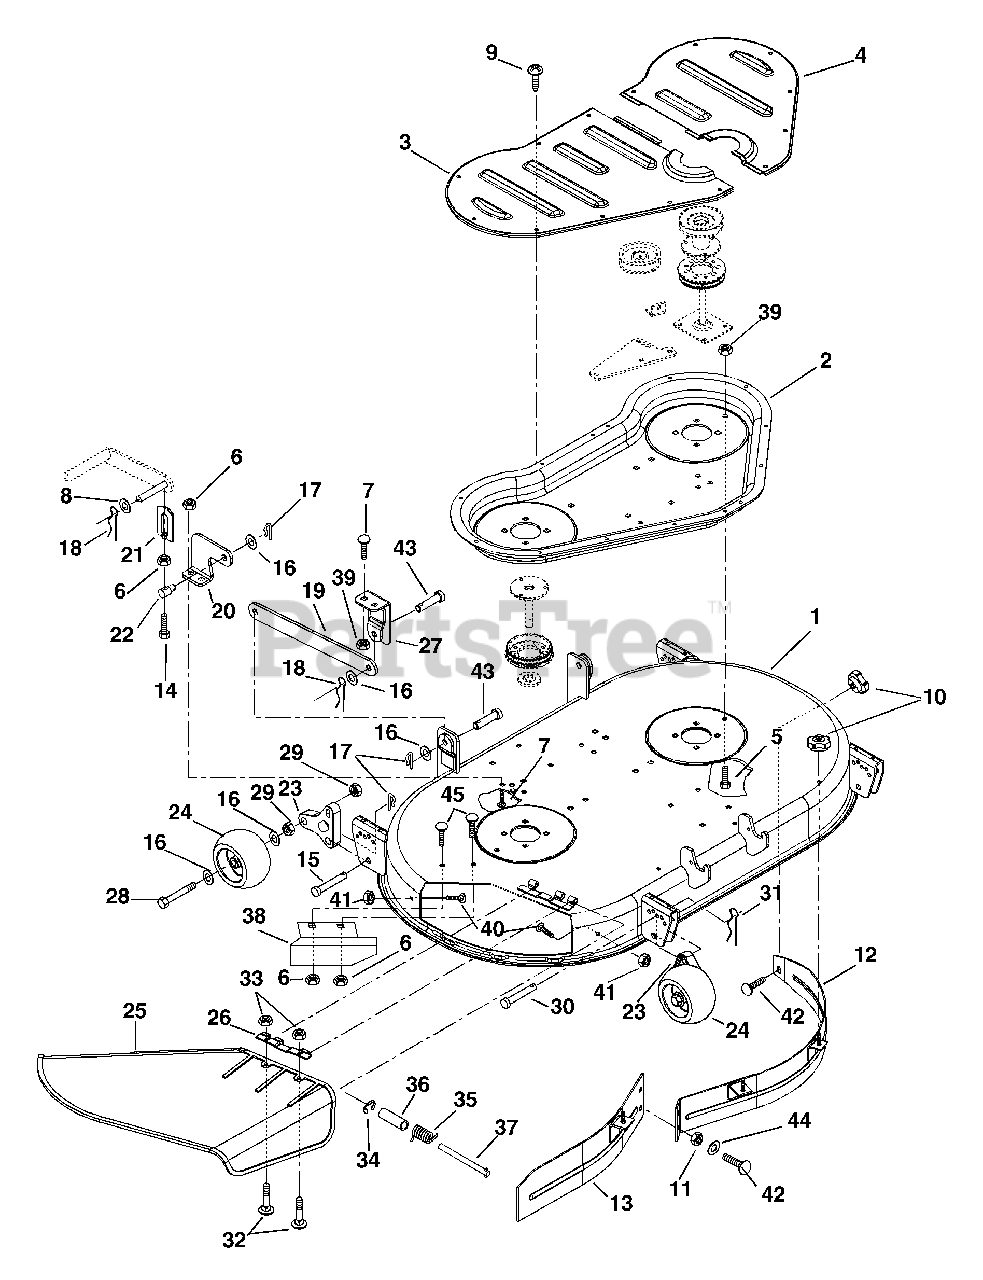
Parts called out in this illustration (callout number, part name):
1	Mower-42" Gravely ZT with Decals
1	Mower-42" Gravely ZT Assembly Complete
2	Reinforcement-Deck
3	Cover-Deck Reinforcement Right Hand
4	Cover-Deck Reinforcement Left Hand
5	Bolt-Hex .38-16 x 1.00
6	Nut-Locking-Center .38-16
7	Bolt Round Head Square Neck .38-16
8	Washer-Flat-Steel .640 x 1.005 x .062
9	Screw-Tapping Hex Washer Head Thread Rolling .31-18 x .50
10	Knob
11	Nut-Lock-Center .31-18
12	Weldment-Baffle Upper Left Hand
13	Weldment-Baffle Upper Right Hand
14	Bolt-Hex .38-16 x 2.50 Grade 5
15	Pin-Clevis .50 x 1.38
16	Washer-Flat-Steel .505 x .88 x .072
17	Clip-Spring
18	Pin-Hair-External .12 x .31 x 2.37
19	Link-Lift
20	Bracket-Lift
21	Link-Adjustment
22	Trunnion
23	Bracket-Roller Bracket Adjustment
24	Wheel 5" x 3"
25	Deflector-Chute 42"
26	Hinge-Plate
27	Weldment-Deck Stop Bracket
28	Bolt-Hex .50-13 x 4.00
29	Nut-Locking-Center-Jam .50-13
30	Pin-Clevis .31 x 1.38
31	Pin-Hair Internal .08 x .38 x 1.42
32	Bolt-Round Head Square Neck .25-20 x .75
33	Nut-Locking-Flange .250-20
34	Ring-Retaining-External .312 x .025
35	Spring-Torsion .095 x .50 x 1.00
36	Bushing
38	Deflector-Baffle
39	Nut-Locking-Nylon .38-16
40	Bolt-Hex .31-18 x .75
41	Nut-Locking-Center .31-18
42	Bolt-Round Head Square Neck .31-18 x .75
43	Pin-Clevis .50 x 1.00
44	Washer-Flat-Steel .038 x .875 x .083
45	Bolt-Hex .38-16 x .075
